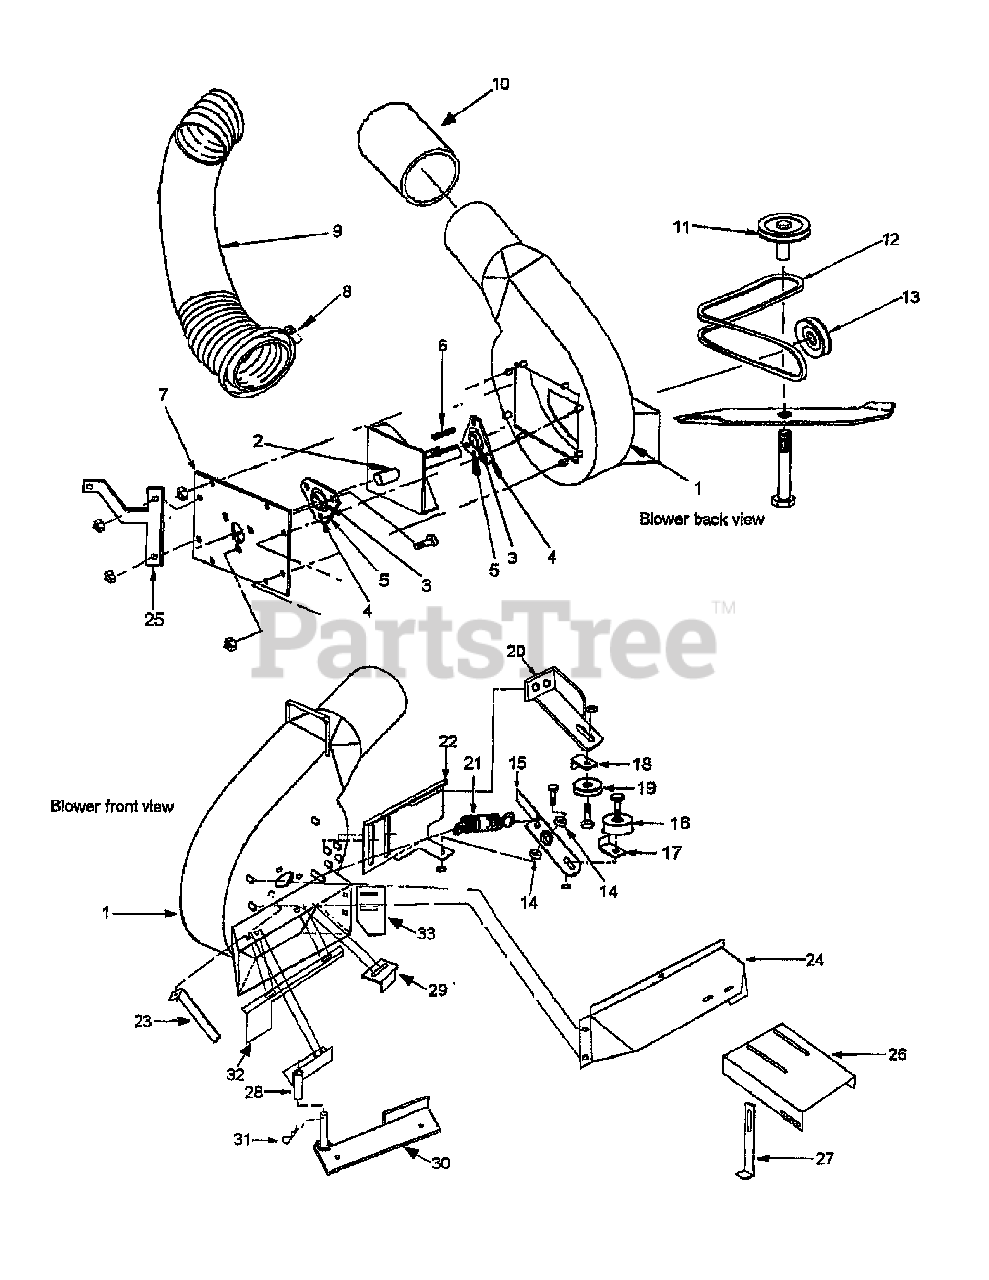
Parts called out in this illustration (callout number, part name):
1	BLOWER CANISTER UNIVERSAL
3	FAN BEARING w/collar for blower back side
4	BEARING FLANGETTE WITH GREASE ZERK
5	BEARING FLANGETTE
6	MACHINERY KEY 1/4" x 1"
7	BLOWER COVER PLATE
8	7" HOSE CLAMP
9	6" HOSE X 46"
10	HOSE INSERT 6"
11	DECK PULLEY - (48", 54" and 80" DECK)
12	BELT INSTA POWER A56
13	BLOWER DRIVE PULLEY 3.5
14	IDLER ARM BEARING
15	IDLER ARM
16	FLAT IDLER PULLEY 3.25"
17	FLAT IDLER PULLEY BRACKET
18	V-IDLER PULLEY BRACKET
19	V-IDLER PULLEY 3.5"
20	V PULLEY BRACKET
21	IDLER SPRING
22	BLOWER PULLEY BRACKET
23	FAN PULLEY BELT BRACKET
24	BLOWER BELT COVER
25	PULLEY BRACKET SUPPORT
26	BELT GUARD
27	BELT GUARD LEG
28	BLOWER MOUNT FRONT
29	BLOWER SUPPORT BRACKET
30	BLOWER MOUNT DECK
31	HAIR SPRING COTTER # 6
32	BLOWER TAB
33	BLOWER BLOCKING PLATE
